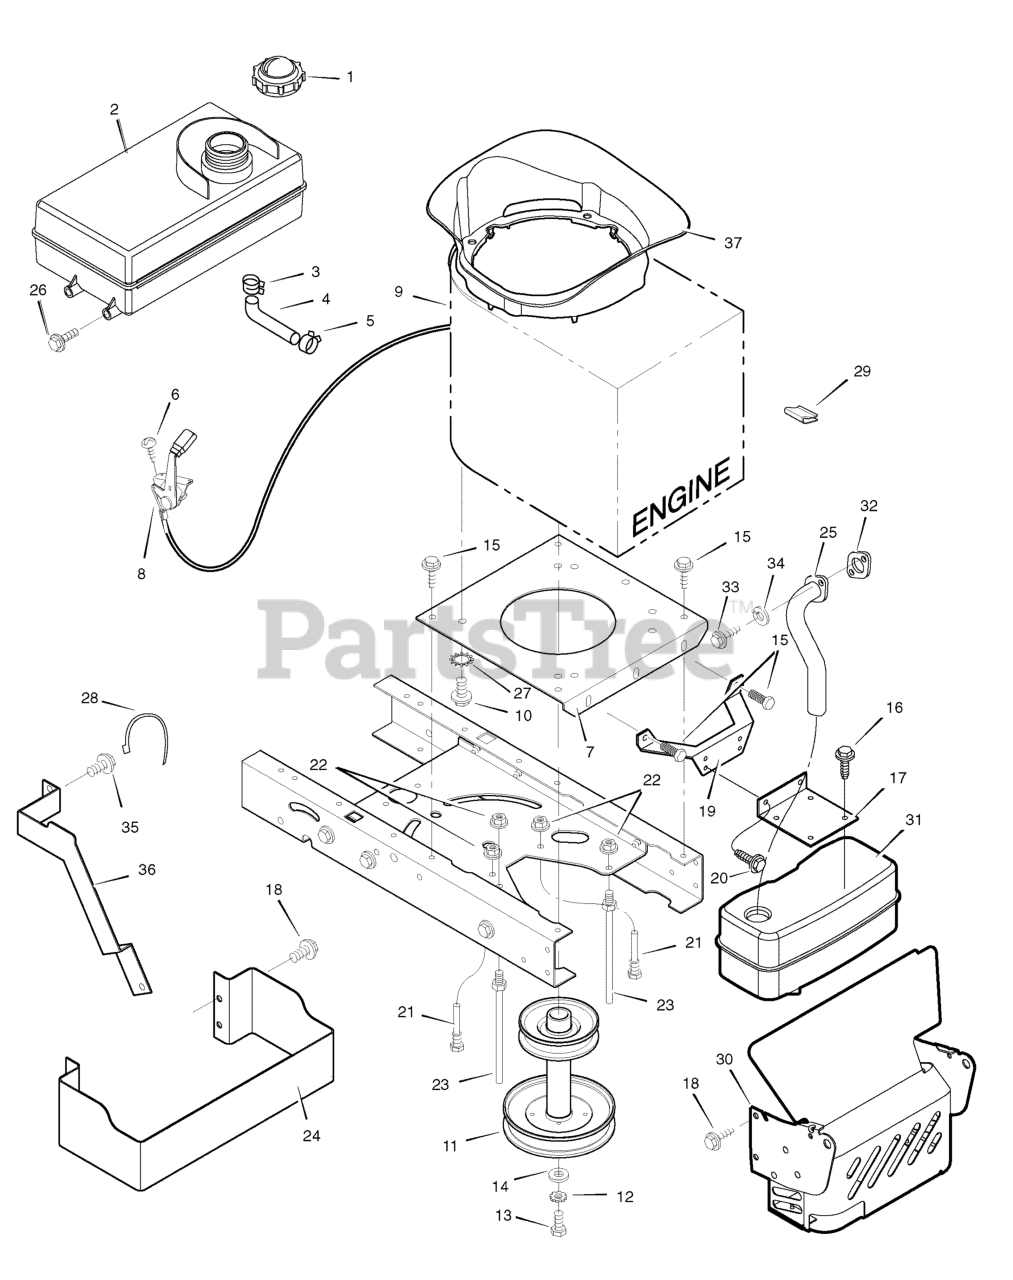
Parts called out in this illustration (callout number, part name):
1	FUEL CAP
2	TANK, Fuel 1.4 Gal.
3	HOSE CLAMP
4	Fuel Line (Must cut to length)
5	HOSE CLAMP
7	PLATE, Engine
8	THROTTLE CONTROL
9	Engine, Briggs & Stratton *
10	BOLT, Engine Mount
11	STACK PULLEY ASSEMBLY
12	LOCKWASHER
13	BOLT, Hex
17	BRACKET, Muffler
19	BRACKET, Muffler Mount
21	GUIDE, Belt
22	NUT, Flange
23	GUIDE, Belt
24	GUARD, Heat Shield
25	EXHAUST TUBE, Single
27	WASHER, Star
28	STRAP, Tie
29	CLIP, Wire Adhesive
30	SHIELD, Heat
31	MUFFLER
32	GASKET, Exhaust
34	WASHER
35	BOLT, Washer Hex Head
36	GUARD, Exhaust Pipe
